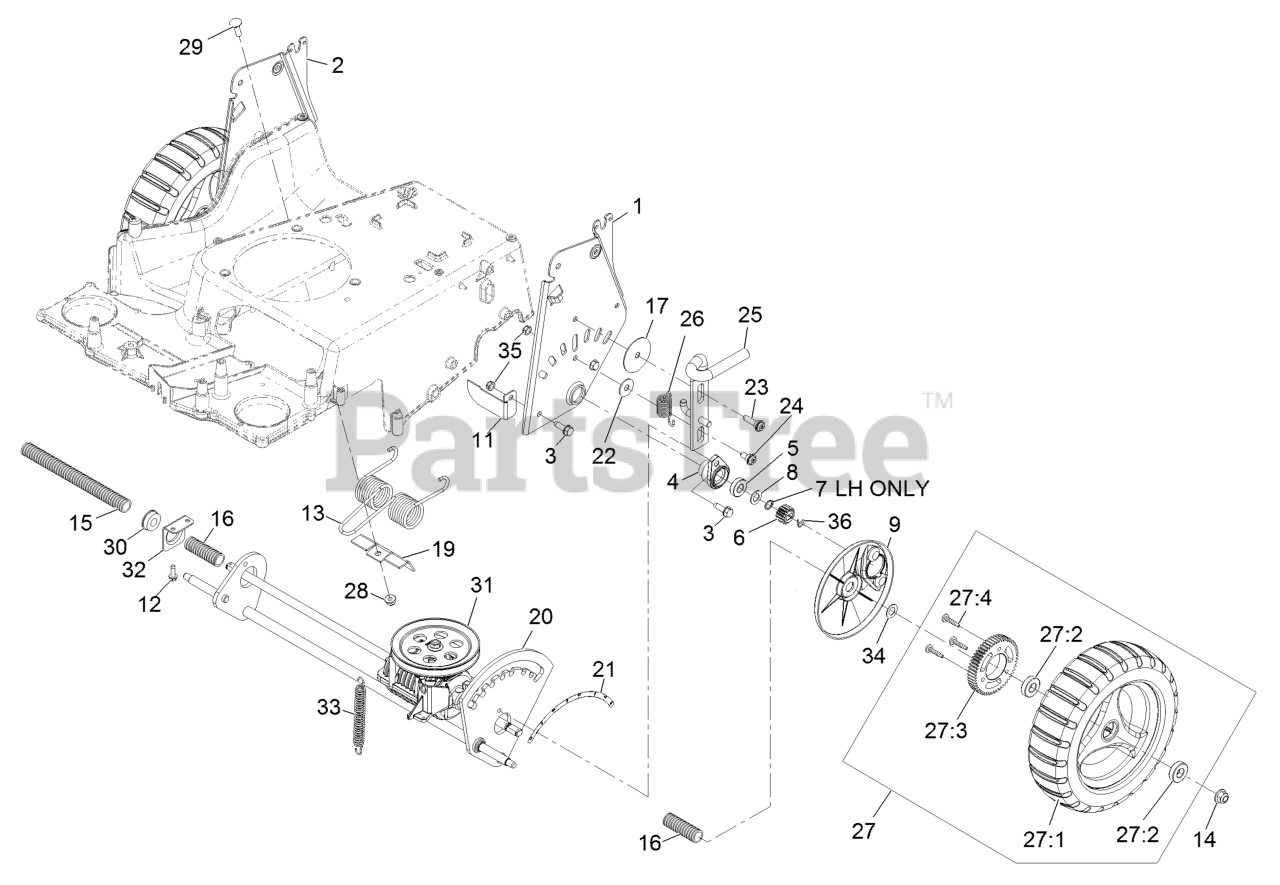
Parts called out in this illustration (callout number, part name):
1	LH HOC PLATE ASM
2	RH HOC PLATE ASM
3	SCREW-THD ROLL, HWH
5	BEARING-BALL
7	RING-RETAINING
8	WASHER-THRUST
9	COVER-GEAR
12	SCREW-HWHTF
13	SPRING-TORSION
14	NUT-HF, NI
15	CONDUIT-CONVOLUTED
16	CONDUIT-CONVOLUTED
17	WASHER-PLAIN
19	BRACKET
21	DECAL-HOC, REAR
23	SCREW-SHOULDER, BHTF
24	BOLT-SHOULDER
25	LOCK-HEIGHT, ADJUST
26	SPRING-EXTENSION
27:2	BEARING-BALL
27:4	SCREW-DRIVE
28	NUT-HF, NI
29	BOLT-CARR
30	BEARING-BALL
33	SPRING-EXTENSION
34	WASHER-PLAIN
35	NUT-LOCK, NI
36	PIN-SNAP
